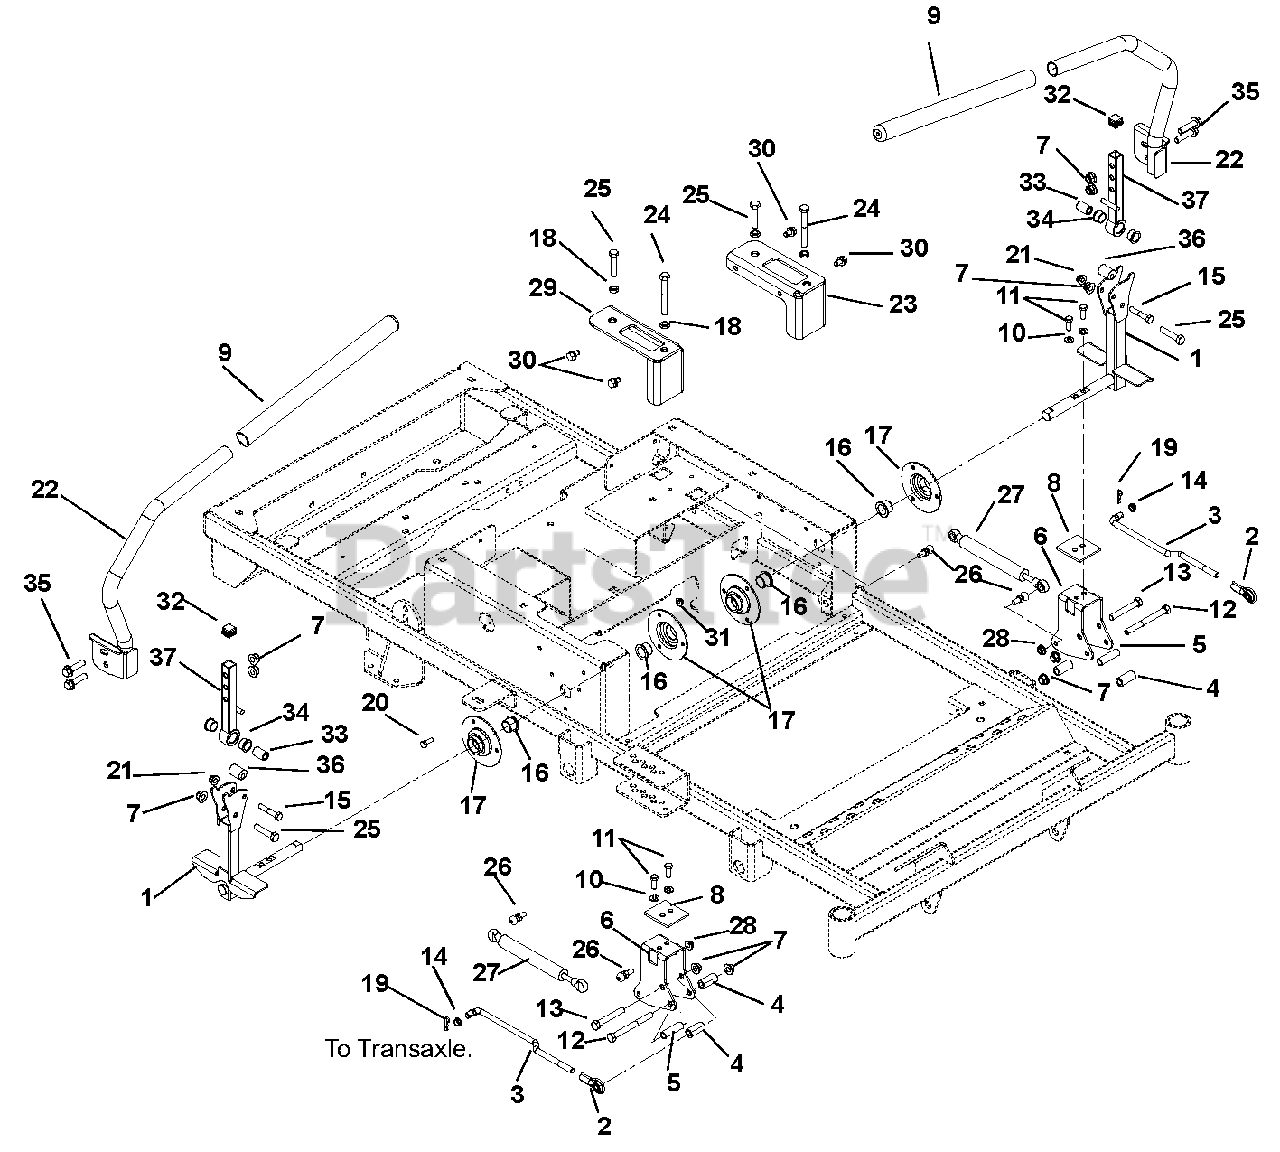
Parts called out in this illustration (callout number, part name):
1	Weldment, Control Arm
2	Rod End, .38 Right Hand
3	Link, Transmission
4	Bushing, Spacer .390 x .625 x 1.25 Promaster
5	Spacer, Steering
6	Bracket, Steering
7	Nut, .38-16 Nyloc Flange
8	Plate, Steering Reinforcing
9	Grip, Handlebar 15" Foam
10	Washer, Locking .31 x .078
11	Bolt, Hex .31-18 x 1.00 Grade 8
12	Bolt, Hex .38-16 x 3.75 Grade 5
13	Bolt, Hex .38-16 x 2.50 Grade 5
14	Bushing, Polyliner 322-C
15	Bolt, Hex .31-18 x 1.75 Grade 5
16	Bushing, Flange .750 x 1.000 x .625 x 1.250
17	Bearing Flange
18	Nut, Hex Jam .375-16
19	Pin, Hair Internal .08 x .18 x 1.18
20	Bolt, Hex .25-20 x .75 Grade 5
21	Nut, .31-18 Nyloc Flange
22	Weldment, Steering Handle Right Hand
23	Bracket, Left Hand Speed Control
24	Bolt, Hex .38-16 x 3.00 Grade 5
25	Bolt, Hex .375-16 x 1.750 Full Thread
26	Stud, Ball
27	Damper, Control
28	Nut, Locking Top Flange .31-18
29	Bracket, Right Hand Speed Control
30	Screw, Tapping .31-18 x .50 Hex Washer Head
31	Nut, Locking Top Flange .25-20
32	Cap Plug, Square .75-14-20 Ribbed
33	Spacer, .375 x .625 x .970 (PM)
34	Bushing, Flange, .625 x .750 x .450 x .875
35	Bolt, Serrated Flange Washer Hex Head .375-16 x 1.5
36	Bushing, Eccentric .31 x .75 x .97
37	Weldment, Upper Control Arm
